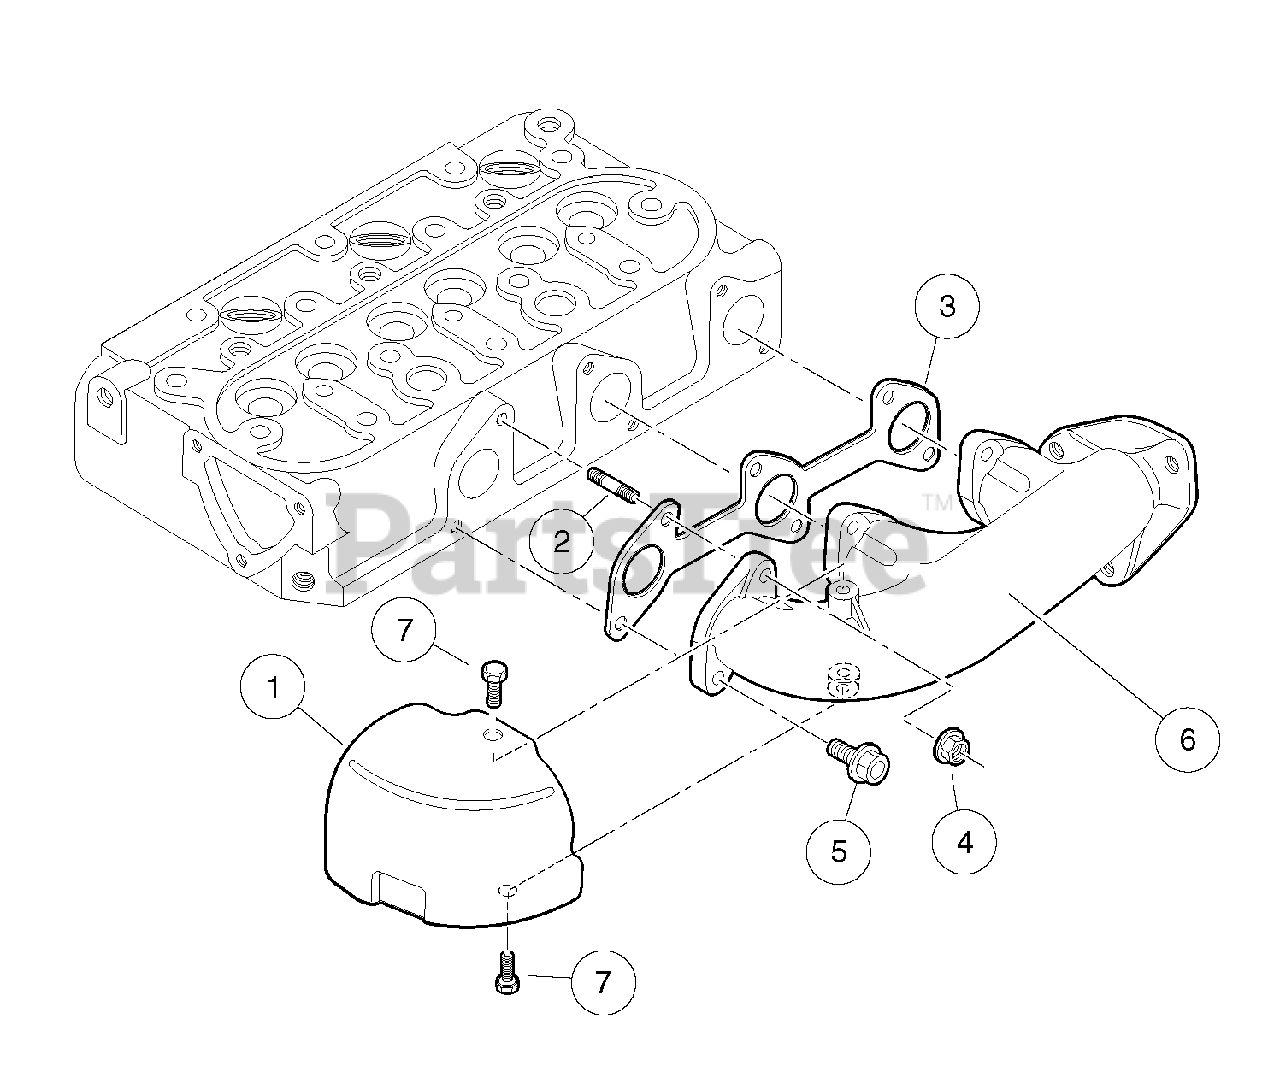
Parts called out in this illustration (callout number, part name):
1	Cover, Heat Proof
2	Stud, M6 X 26
3	Gasket, Ex-manifold
4	Nut, Flange, M6, Ubs
5	Bolt, Flange Head, M6 X 1 X 16
6	Manifold, Exhaust, D722
7	Bolt, D722, Exhst Manfld Cover
